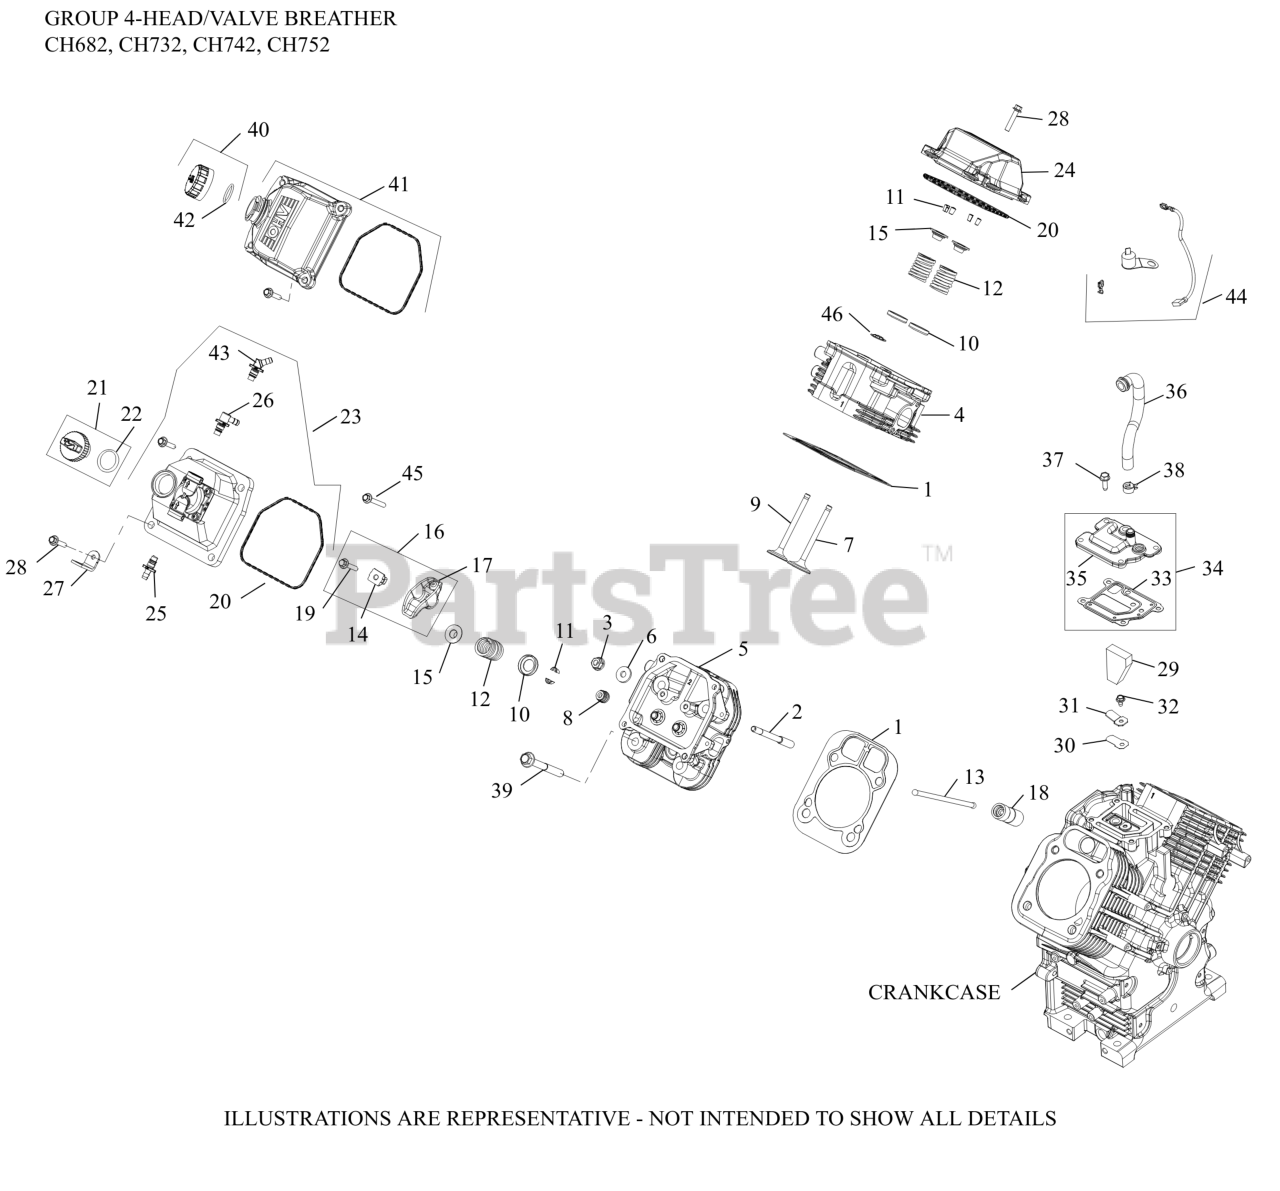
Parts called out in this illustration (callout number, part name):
1	KIT, GASKET CYLINDER HEAD
2	STUD, M8X1.25
3	NUT, FLG M8X1.25
4	KIT, CYLINDER HEAD #1-(#24318218S)
5	KIT, CYLINDER HEAD #2-(#24318219S)
6	WASHER, FLAT 8.6 MM
7	VALVE, INTAKE (STD)
7	VALVE, INTAKE (.25)
8	SEAL, VALVE BAND
9	VALVE, EXHAUST (STD)-USE 32 016 01-S
9	VALVE, EXHAUST (.25)
10	RETAINER, SPRING
11	KIT, RETAINER
12	SPRING, VALVE
13	ROD, PUSH
14	PIVOT, ROCKER ARM
15	CAP, VALVE SPRING
16	KIT, VALVE TRAIN
17	ARM, ROCKER
18	LIFTER, VALVE HYDRAULIC-USE 25 351 11-S
19	SCREW, FLG (BLACK) M6X1.0X34
20	O-RING (YELLOW), VALVE CO
21	CAP ASSY, OIL FILL (YELLOW)
23	KIT,VALVE COVER-FUEL PUMP
24	KIT, VALVE COVER-PLAIN (PLASTIC)
25	KIT, STRAIGHT FITTING
27	STRAP, LIFTING
28	SCREW, FLG M6X1.0X30
29	FILTER, BREATHER
30	REED, BREATHER-(#2440206S)
30	REED, BREATHER
31	RETAINER, REED
32	SCREW, FLG THD FRM M5X.8X10
33	GASKET, BREATHER
34	KIT, BREATHER ASSEMBLY
36	HOSE, BREATHER (HORIZONTAL)
37	SCREW, THREAD FORMING
43	KIT, 45 DEG. FITTING
NI	RETAINER, VALVE GUIDE (KM)
